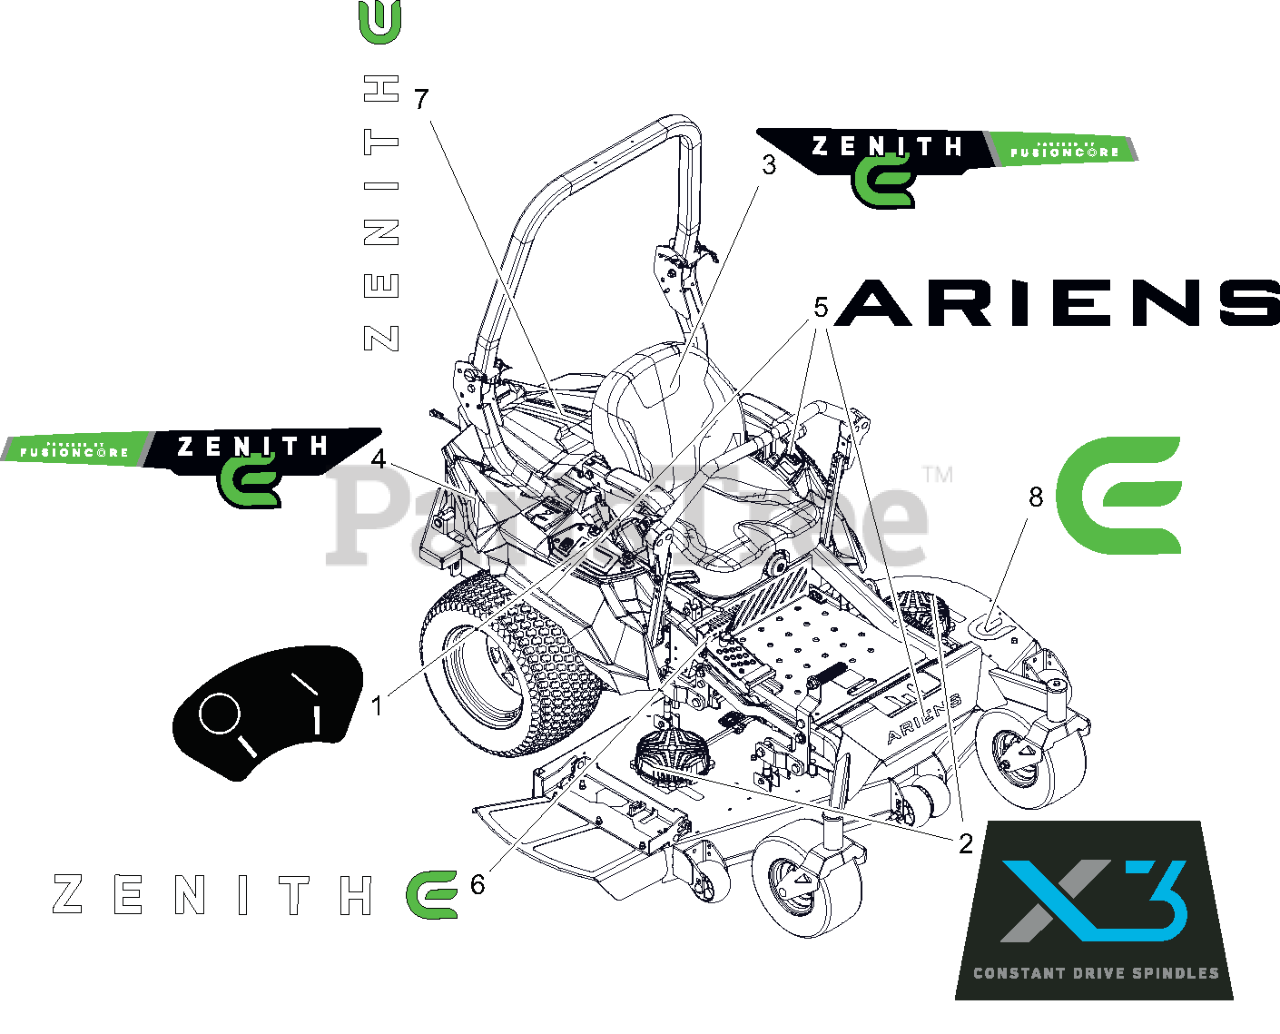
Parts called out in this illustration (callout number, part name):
1	DECAL, KEY SWITCH - 2 POS
2	DECAL, DECK MOTOR
3	DECAL, FENDER - ZENITH LH
4	DECAL, FENDER - ZENITH RH
5	DECAL, ARIENS - 12.0"
6	DECAL, KICKPLATE - ZENITH
7	DECAL, HOOD - ZENITH
8	DECAL, ZENITH - E
